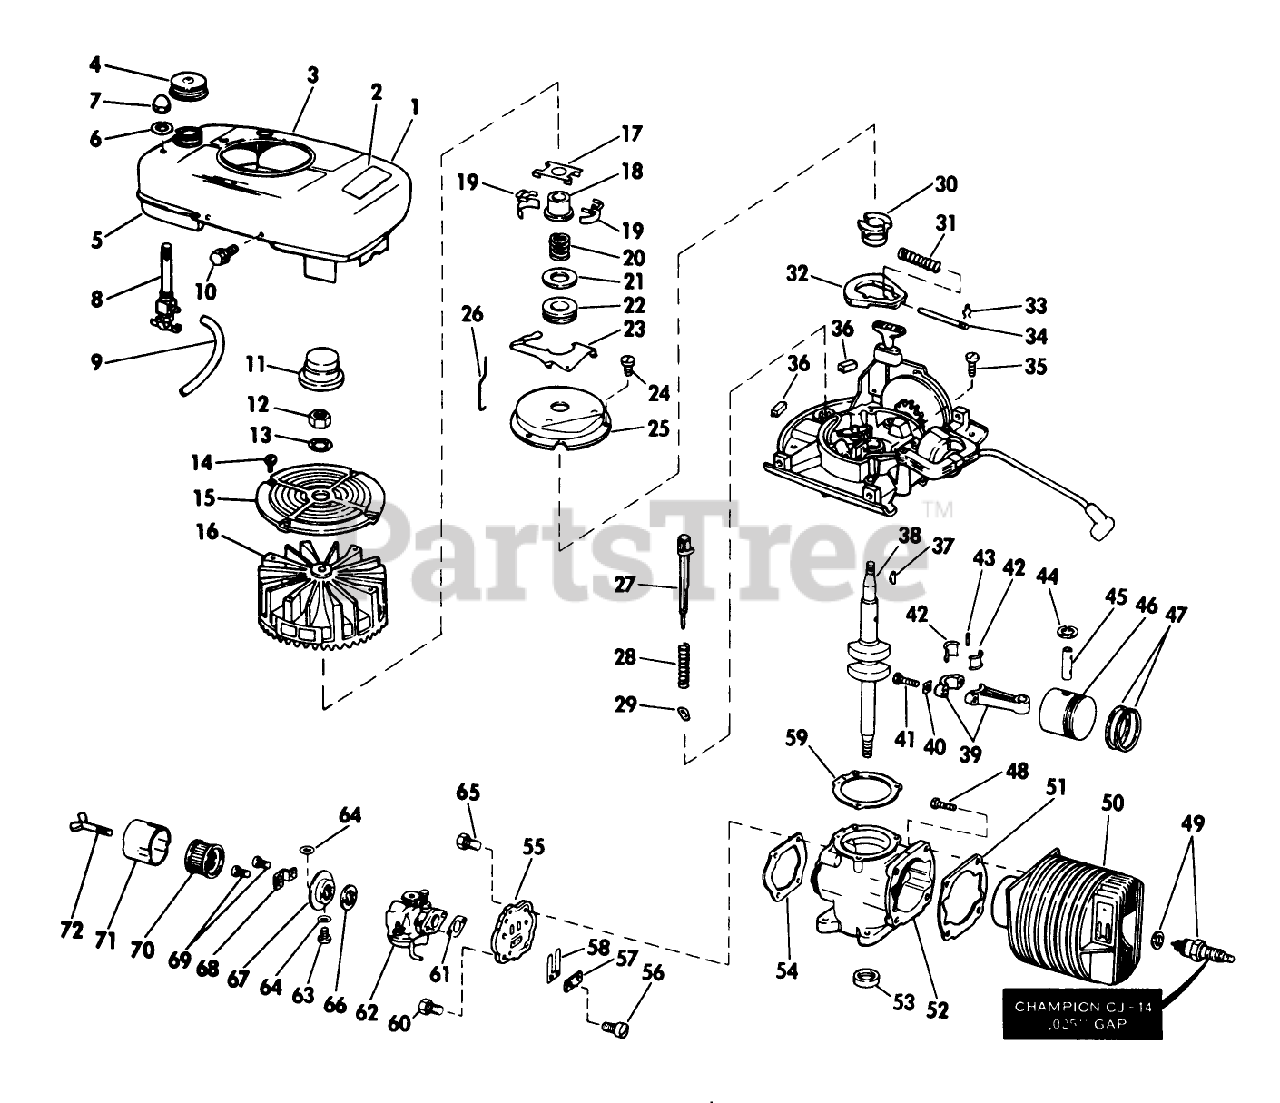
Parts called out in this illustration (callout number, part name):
7	PALNUT S
8	VALVE&SCREEN SM
10	SCREW S
14	SCREW F
16	FLYWHEEL S
18	COLLAR S
22	THRUST COLLAR S
23	LEVER-GOVERNOR S
24	SCREW S
25	DUST COVER S
28	SPRING S
30	SPARK ADV. S
31	SPARK ADV. SPRING S
32	FLYWEIGHT S
33	SPARK ADJ. SPRING
34	PIN,SPARK ADV. S
42	LINER ASM
44	RING-RETAINING
49	Spark Plug Gasket (Champion CJ-14, .025" Gap)
51	GASKET S
54	GASKET S
55	REED PLATE AY. S
57	PLATE-BACKUP, REED
59	GASKET S
60	SCREW S
61	GASKET S
65	SCREW S
66	GASKET S
